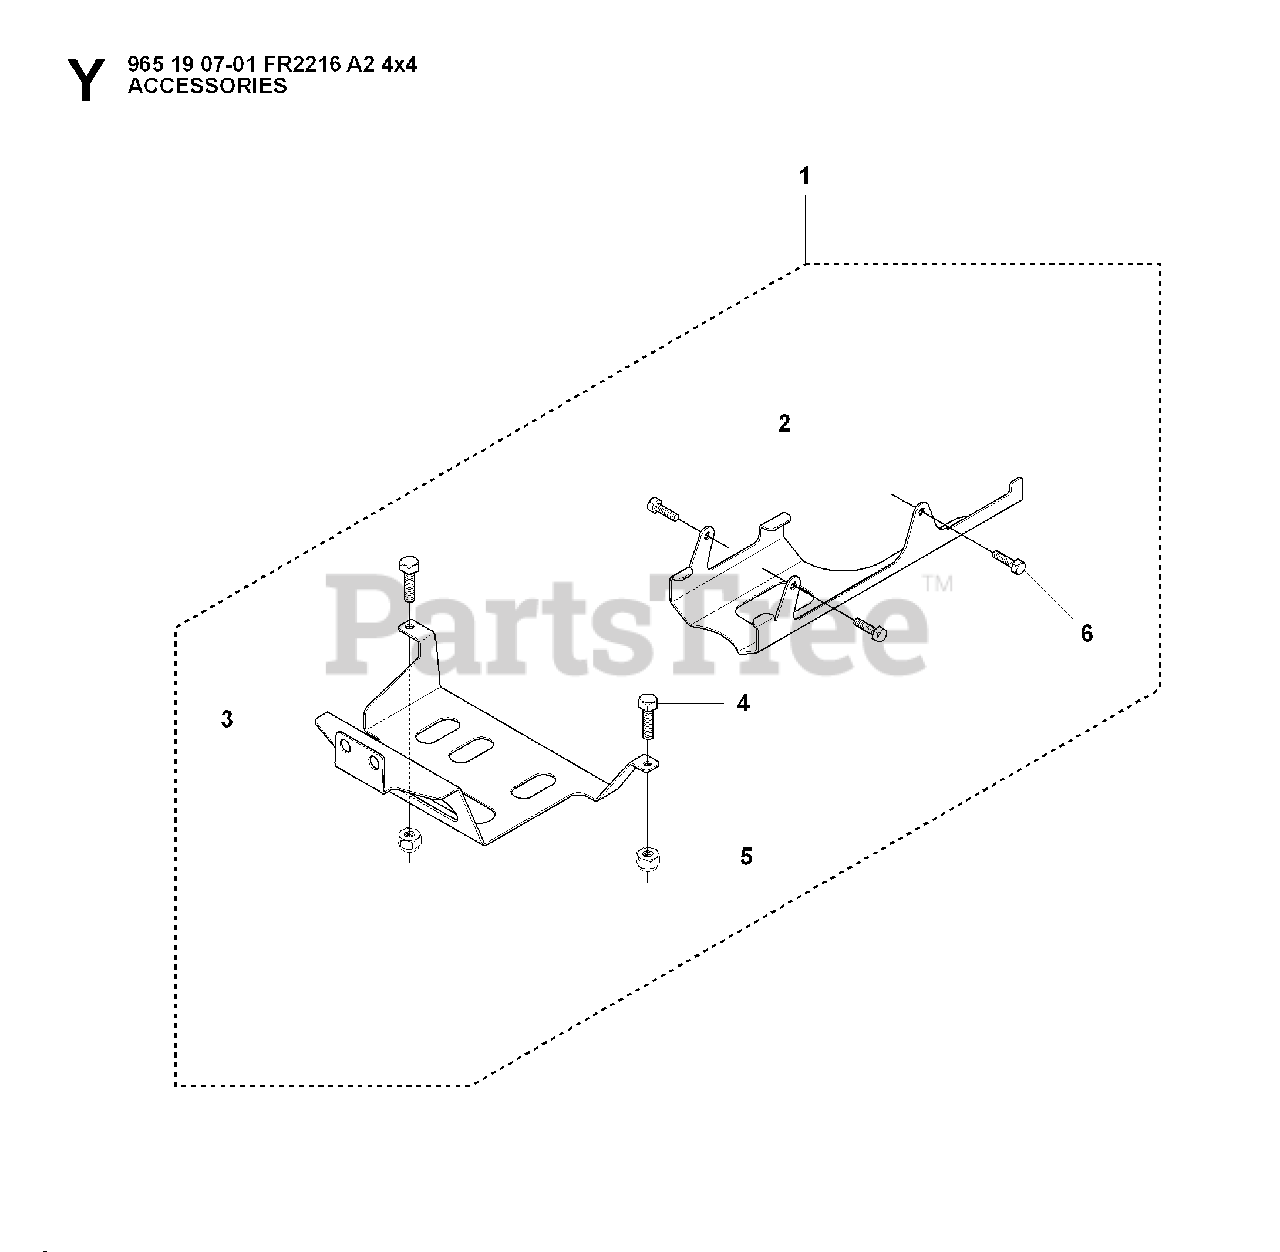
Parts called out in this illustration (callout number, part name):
3	RP PROTECTION PLATE REAR
5	LOCKNUT M8
6	BOLT FLANGE - M8X16
